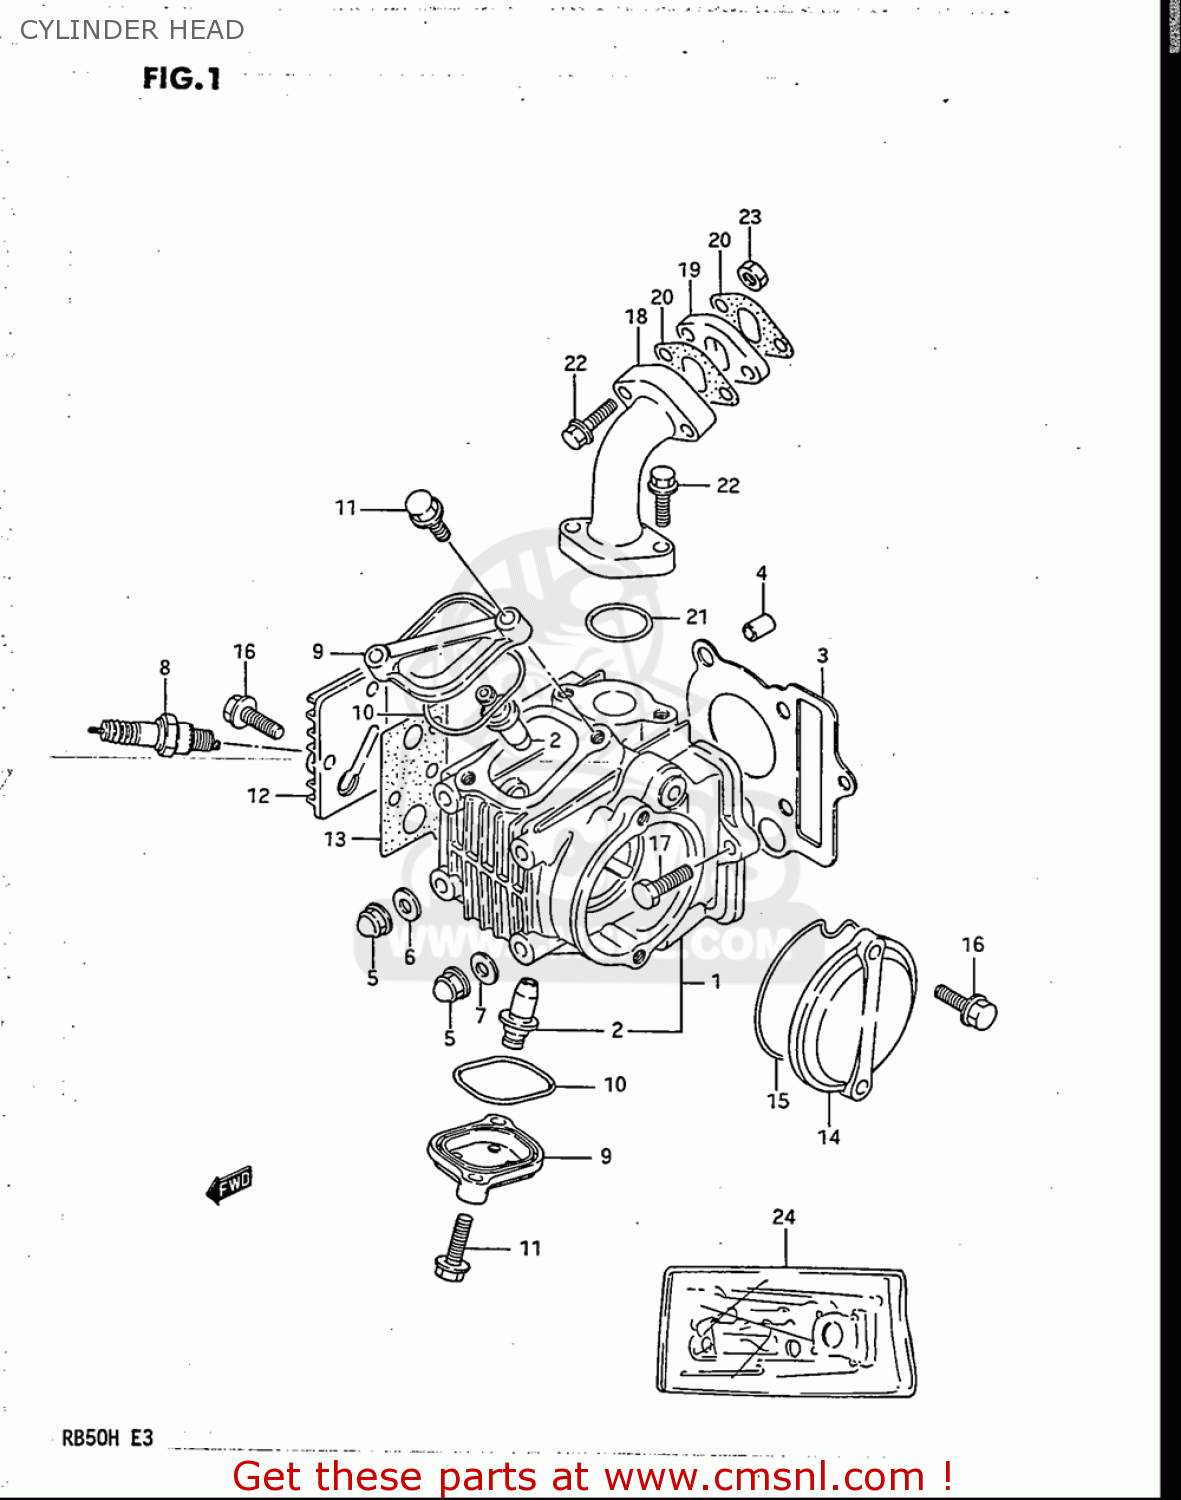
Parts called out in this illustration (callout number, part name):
2	GUIDE,VALVE
3	GASKET,CYLINDER HEAD (NAS)
4	PIN(6.2X8X11)
5	NUT
7	WASHER(6.5X14X2.3)
8	SPARK PLUG C6HA
11	BOLT
13	GASKET,CYLINDER HEAD COVER
14	COVER,CYLINDER HEAD,LEFT
15	O RING(D:2.4,ID:73.5)
16	BOLT
17	BOLT
18	PIPE,INTAKE
19	INSULATOR,CARBURETOR
20	GASKET,CARBURETOR (NAS)
21	O RING(D:2.4,ID:23.7)
22	BOLT
23	NUT
